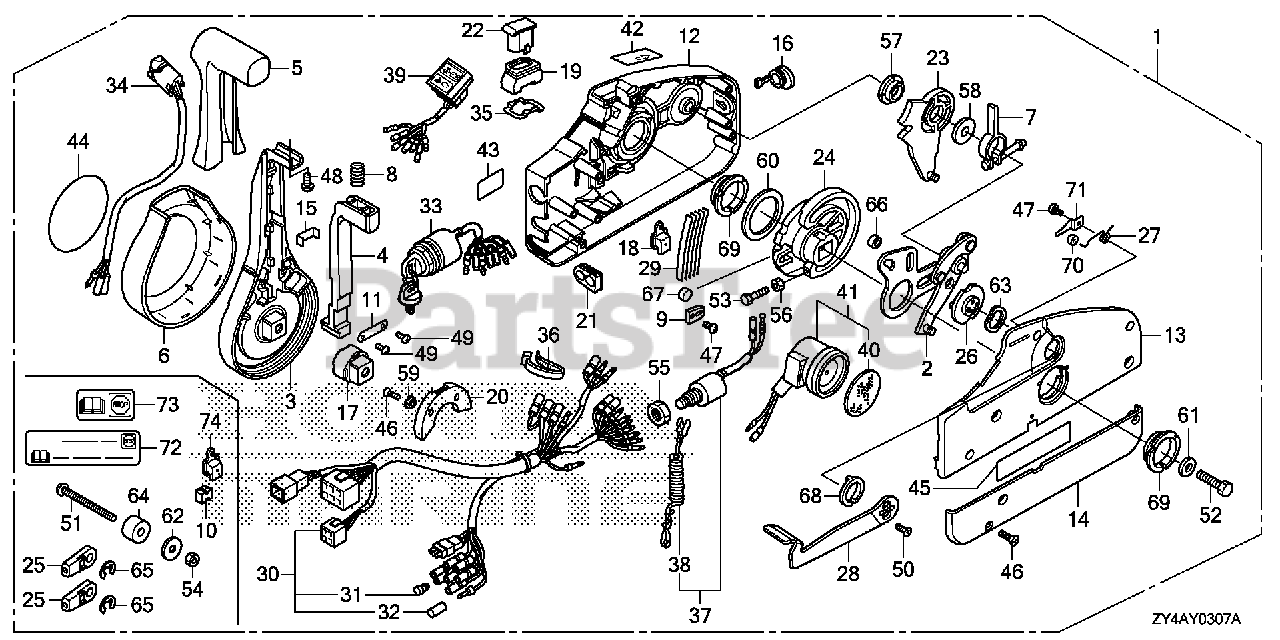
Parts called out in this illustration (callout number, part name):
1	BOX ASSY., REMOTE CONTROL (NHK MEC)
1	BOX ASSY., REMOTE CONTROL (TROLLING CONTROL)(NHK MEC)
2	PLATE ASSY.
3	LEVER, HAND
4	ARM, NEUTRAL LOCK
5	GRIP
6	COVER, LEVER
7	ARM ASSY., BRAKE
8	SPRING (2)
9	CLIP, DETENT
10	SPACER (1) (LOOSE PARTS)
11	BRACKET
12	HOUSING, FR.
13	HOUSING, RR.
14	PANEL, BACK
15	BRACKET, WIRE CLAMP
16	CAP, RUBBER
17	ADJUSTER
18	COVER, POWER TRIM-TILT WIRE
19	SEAL, RUBBER
20	HOLDER, NEUTRAL LOCK
21	GROMMET, WIRE (14)
22	CAP, TROLLING CONTROL SWITCH BLANK
23	GEAR ASSY., SHIFT
24	GEAR, DRIVE
25	TERMINAL, CABLE (LOOSE PARTS)
26	DRUM ASSY., FREE THROTTLE
27	SPRING (1)
28	LEVER, FREE THROTTLE
29	SPRING, DETENT
30	CABLE ASSY., REMOTE CONTROL (B)
31	PLUG, CONNECTOR (INNER)
32	PLUG, CONNECTOR (OUTER)
33	SWITCH ASSY., COMBINATION
34	SWITCH ASSY., POWER TRIM-TILT
35	PLATE, SWITCH
36	BAND, WIRE
37	SWITCH ASSY., EMERGENCY STOP
38	WIRE, EMERGENCY
39	LAMP ASSY., INDICATION
40	PLATE, TURN SIGNAL BUZZER
41	BUZZER, WARNING
42	MARK, FAST IDLE
43	MARK, EMERGENCY STOP (US)
44	MARK, EMBLEM
45	LABEL, SIGP
46	SCREW (5X18)
47	SCREW (4X6)
48	SCREW (5X10)
49	SCREW (4X10)
50	SCREW (5X12)
51	SCREW (6X90) (LOOSE PARTS)
52	BOLT (8X50)
53	BOLT (5X25)
54	NUT (6MM) (LOOSE PARTS)
55	NUT, HEX. (16MM)
56	NUT (5MM)
57	BEARING (1)
58	WASHER (3)
59	WASHER (4)
60	WASHER (5)
61	WASHER (8MM)
62	WASHER (7) (LOOSE PARTS)
63	WASHER, WAVE
64	SPACER (2) (LOOSE PARTS)
65	E-RING (6MM) (LOOSE PARTS)
66	ROLLER, DRIVE GEAR CAM
67	ROLLER
68	BEARING (2)
69	BEARING (3)
70	ROLLER, FREE THROTTLE
71	CLIP, ROLLER
72	MARK, EMERGENCY STOP (US) (LOOSE PARTS)
74	COVER, POWER TRIM-TILT WIRE (LOOSE PARTS)
